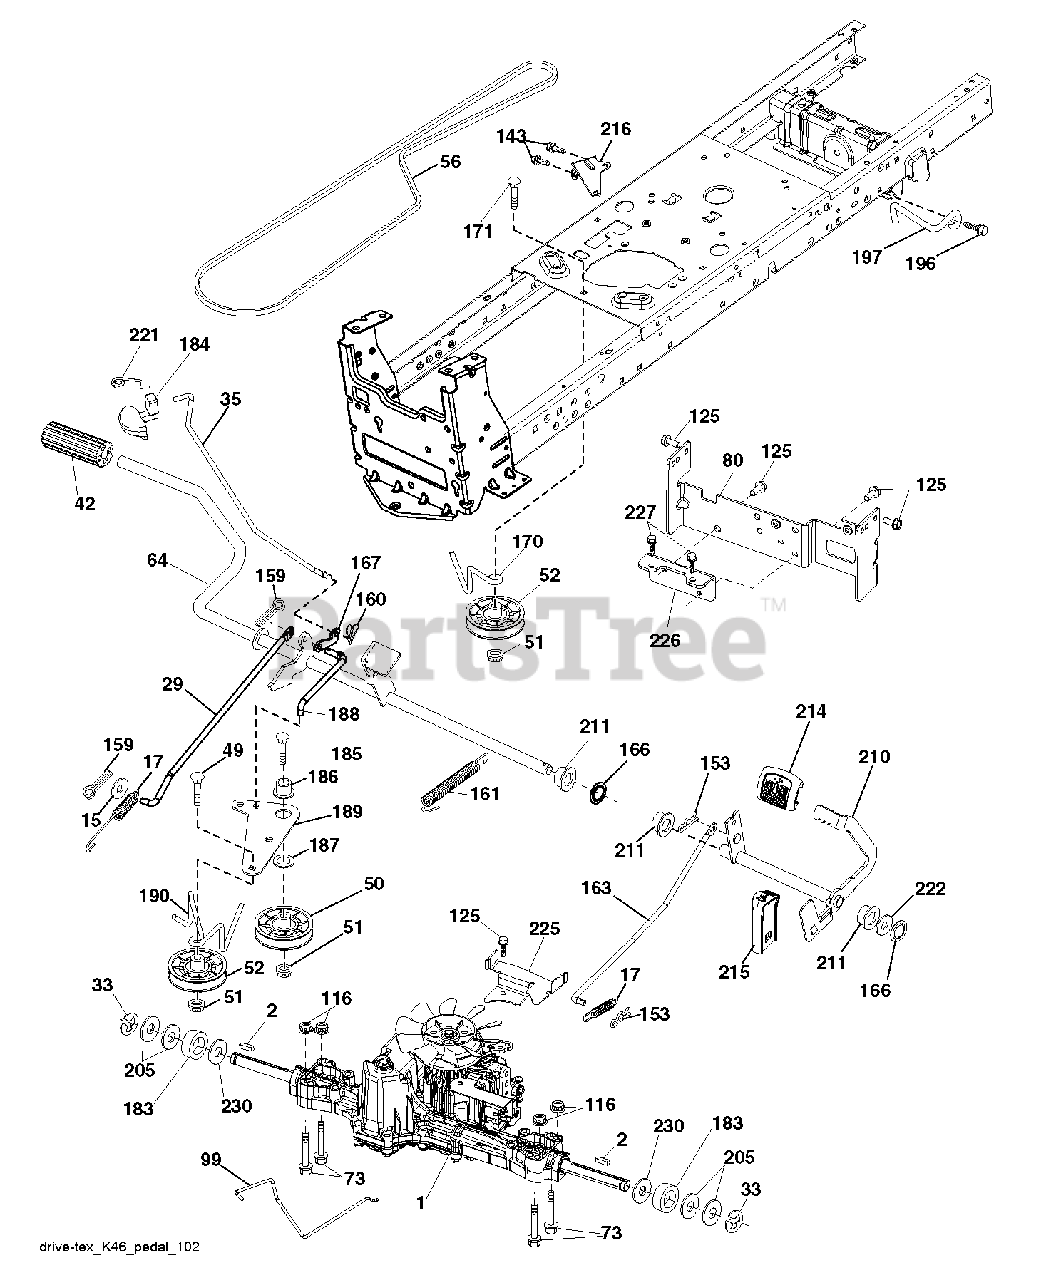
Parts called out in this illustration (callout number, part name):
2	SQUARE KEY
15	WASHER
17	SPRING.BRAKE.K46.GREEN
29	ROD.BRAKE.K46
35	ROD.CNTRL.PARK.PREDATOR.LT.TEX
42	PEDAL COVER T
50	IDLER.FLAT.910.OFFSET
51	NUT LOCK FLG 3/8-16 UNC
52	IDLER.V-GROOVE.910.OFFSET
56	V-BELT.MOWER.92.40.42/K46
64	SHAFT.ASM.PEDAL.BRK.CNTR
80	STRAP.TORQUE.K46.K57R.TT
99	ROD.SPRING.BYPASS.K46.LT.Z
116	NUT LOCK HEX FLANGE 5/16-18
125	SCREW
143	SCREW LT
153	RETAINER M
159	COTTER PIN
160	RETAINER CLIP
161	SPRING, RETURN LT
163	ROD.CONTROL.PEDAL.K46
166	NUT.PUSH.625
167	LATCH.BRAKE.SPRING
170	KEEPER.V-IDLER.CENTER.
183	SPACER AXLE
184	HANDLE.PARKING.BRK.PRED.LT.RED
186	SPACER.RETAINER
187	WASHER 12/32X2X10GA
188	RP LINK.CLUTCH.GROUND.DRIVE
189	BELLCRANK.GROUND.DRIVE.TEX.
190	KEEPER.BELLCRANK.DRIVE
196	SCREW 3/8-16X1
197	LINK.CLUTCH.ANIT-ROTAT
210	ROCKER.ASM.PEDAL.CONTR
211	BEARING.NYLON
214	PEDAL.FORWARD.PAD.TEX
215	PEDAL.REVERSE.TEX.GT.4
216	BRACKET.PULLEY.IDLER.W/TEX
221	RETAINER.SPRING.CLIP.H
222	WASHER 21/32 X 1-1/4 X 10 GA.
225	KEEPER.BELT.TRANSAXLE.K46
226	BRACKET.MOUNT.TORQUE.K46.TLT
227	SCREW
230	WASHER.HARDENED
